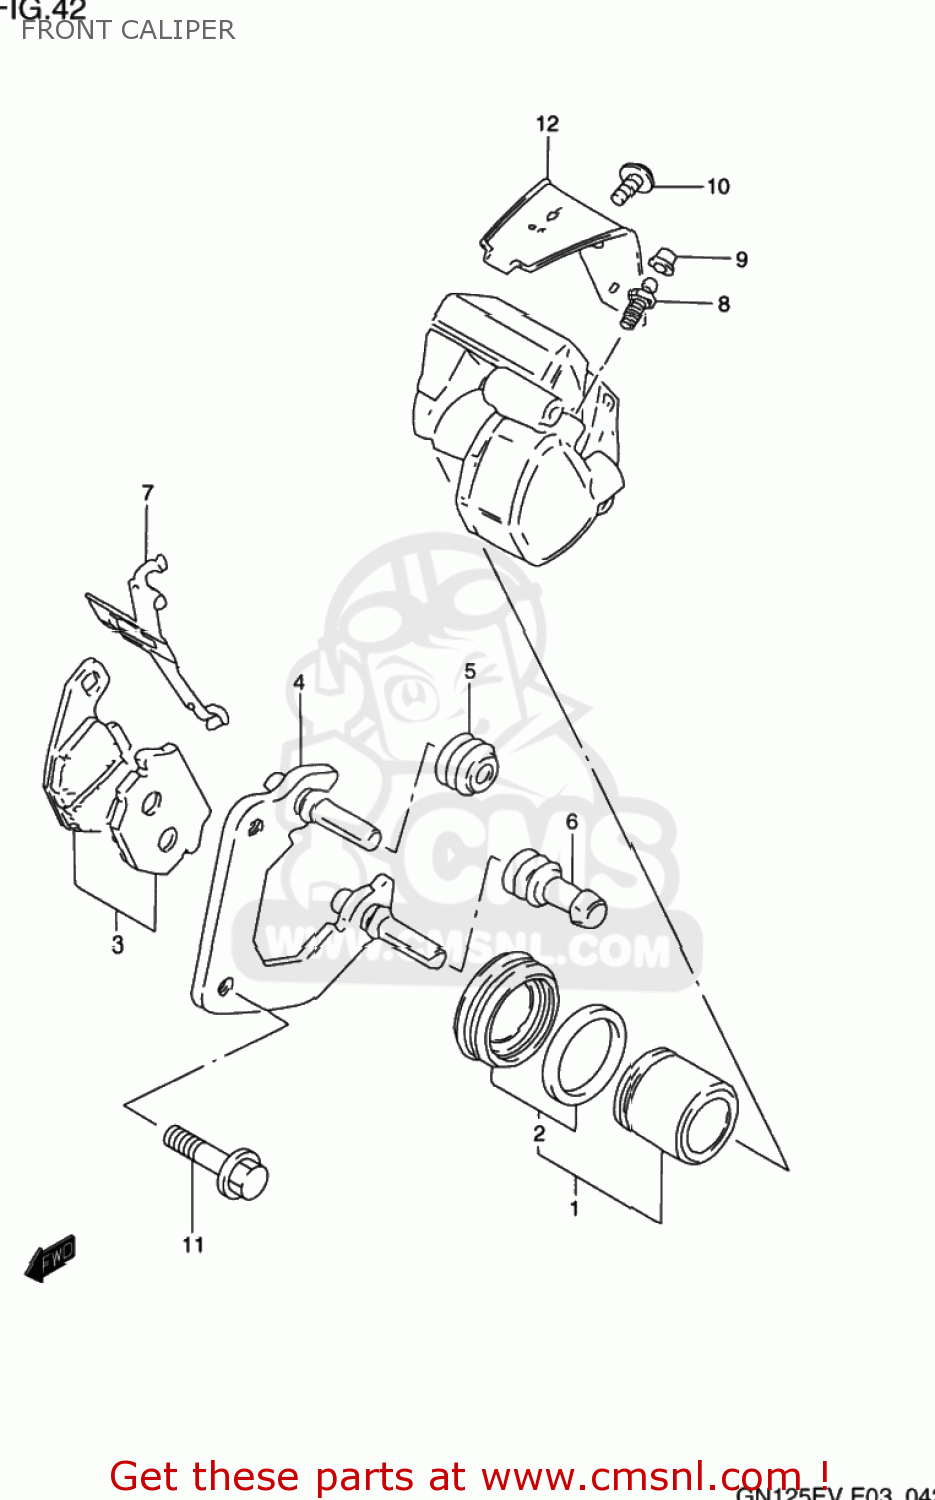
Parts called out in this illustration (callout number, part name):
1	PISTON SET
2	SEAL SET,PISTON
3	PAD SET (NAS)
4	CARRIER,L
5	BOOT,AXLE
6	INSULATOR,AXLE
7	SPRING,PAD
8	BLEEDER
9	CAP,BLEEDER PLUG
10	SCREW
11	BOLT
12	PROTECTOR,CALIPER
